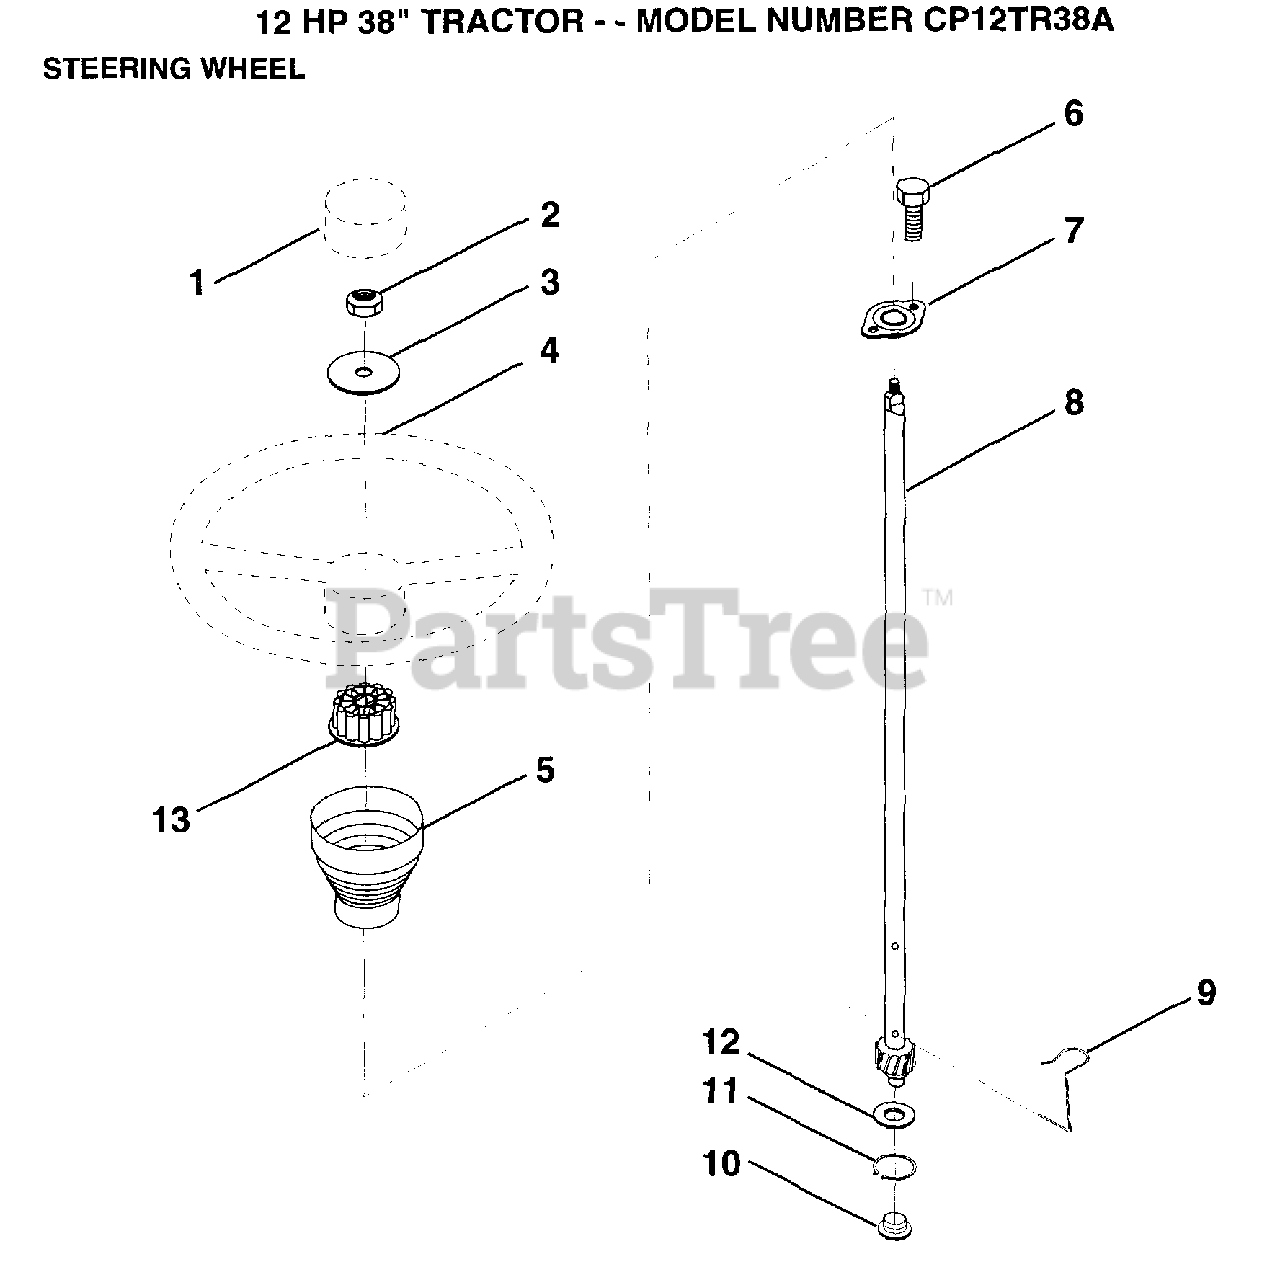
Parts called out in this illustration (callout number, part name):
1	ST WHL INSERT CAP
2	GRIPCO NUT
3	WASHER T
5	SLEEVE STEERING
9	STEERING CLIP
10	BUSHING STEER LWR
11	RING
12	WASHER LT
13	ADAPTER-WHEEL LT
